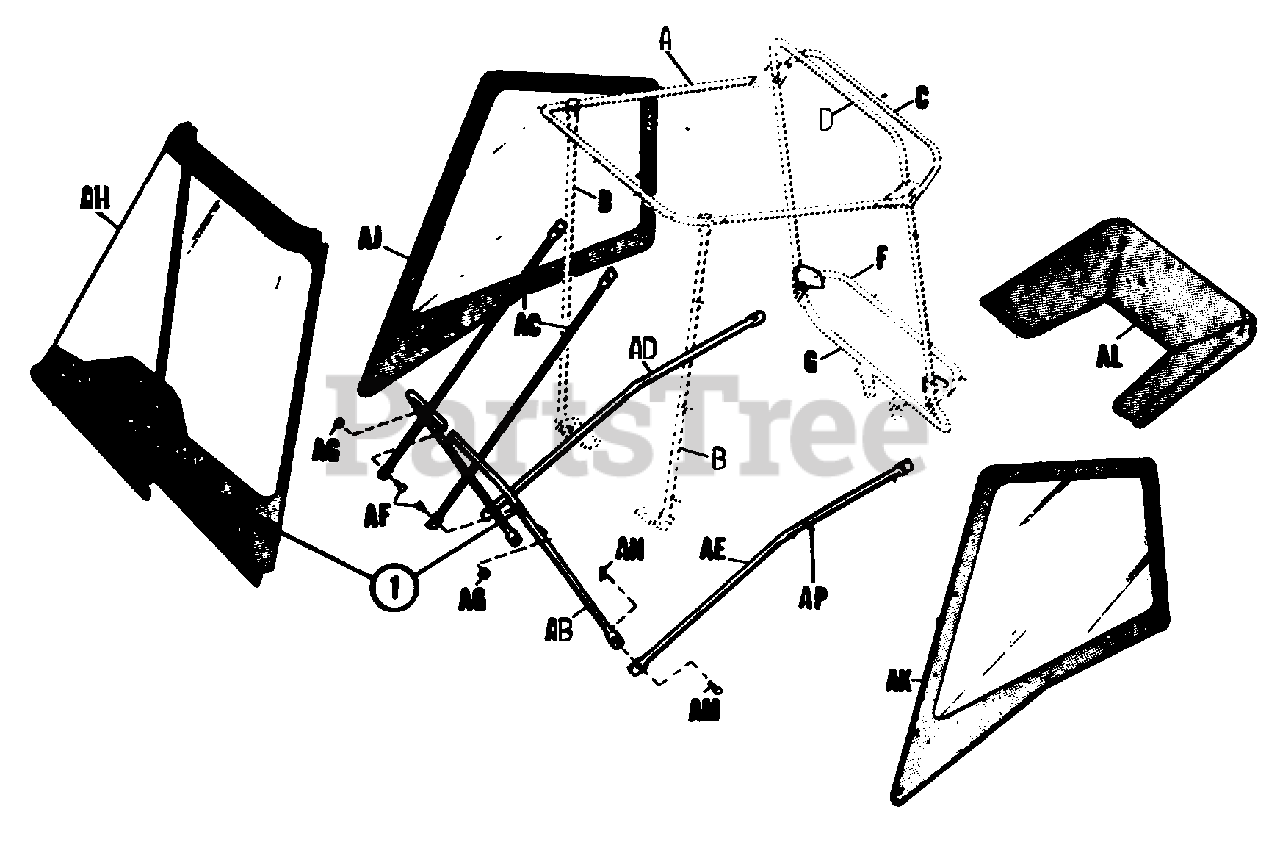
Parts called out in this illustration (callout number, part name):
AB	Frame, Hood
AC	Brace, Front
AD	Brace, Bottom, Right Hand
AE	Brace, Bottom, Left Hand
AF	HexCapscrew, 1/4-20 x 1-1/4" lg.
AG	Hex Lock Nut, 1/4-20
AH	Windshield
AJ	Enclosure, Right Hand
AK	Enclosure, Left Hand
AL	Enclosure, Rear
AM	Drilled Screw
AN	Spring Clip
AP	Single Stud Lift-O-Dot
